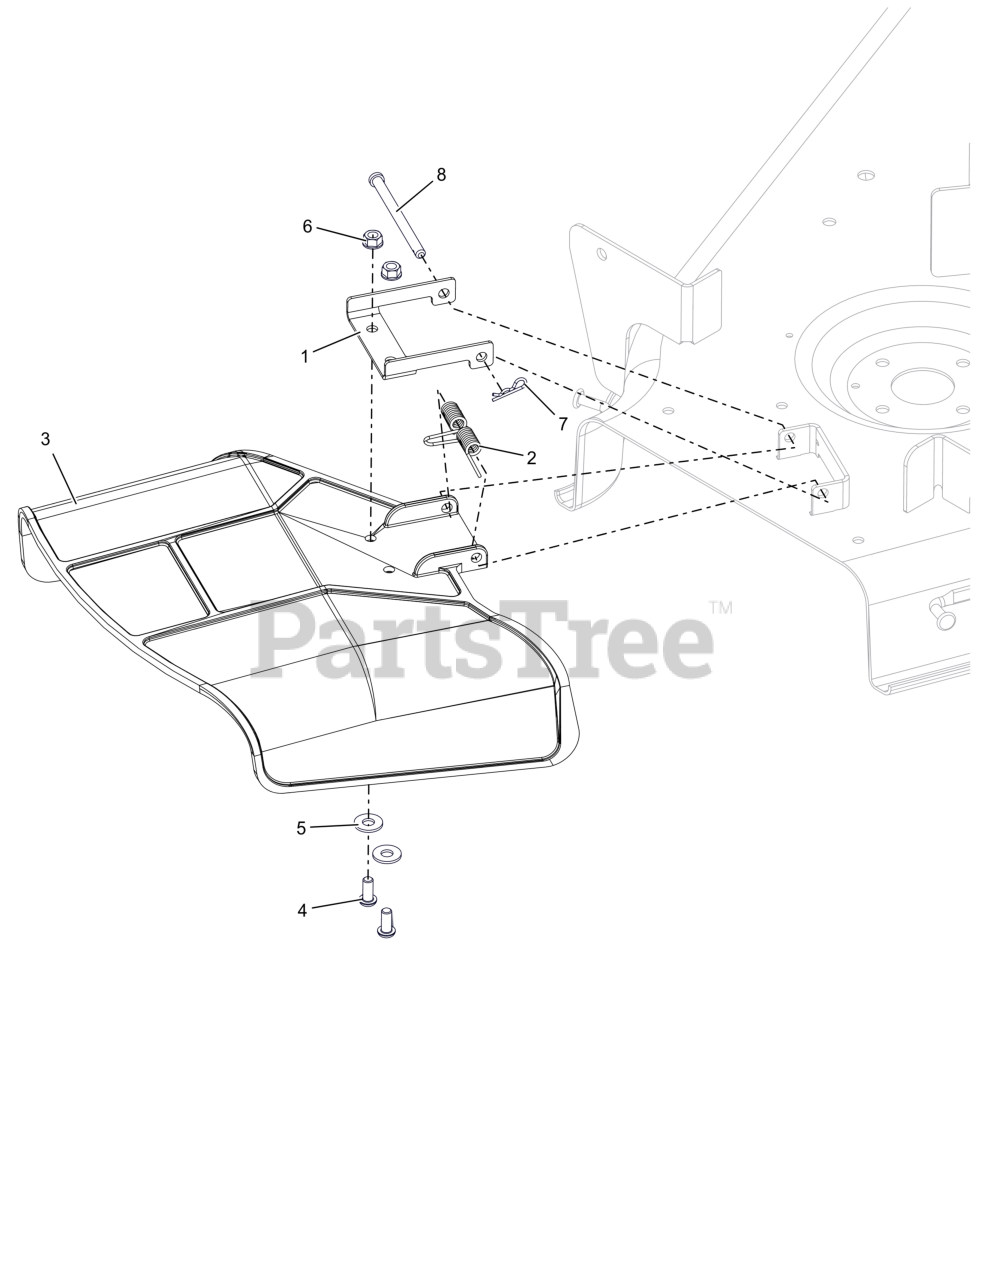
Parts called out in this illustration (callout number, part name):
1	BRKT, CHUTE REINFORCEMENT
2	SPRING, TORSION
3	CHUTE, SIDE DISCHARGE
4	SCR-SKH .31-18X.75 BTNHD YWZC
5	WSHR,FLT .375X.875X.083 ZCC
6	NUT,LK-CTR-FLG .31-18 GF ZCC
7	PIN, HAIR #213 .08X1.19 ZCC
8	PIN, 5/16 X 3.88"
